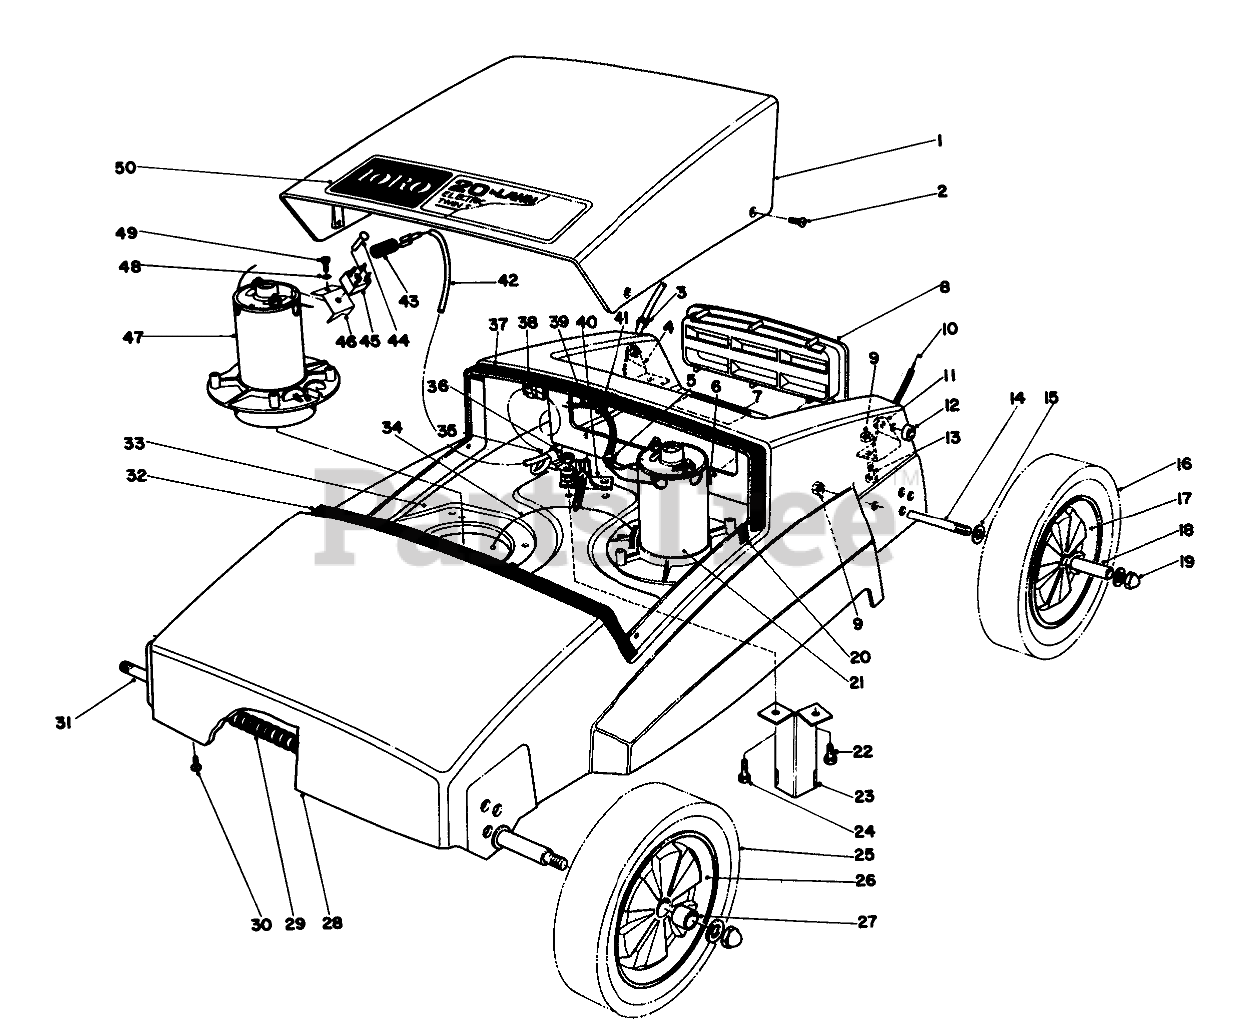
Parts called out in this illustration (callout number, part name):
1	Cover
3	5/16 ID BSHG
4	Handle Bracket R.H.
5	TIE-CABLE
6	Nut-Push On
7	Decal-Warning
8	Louver
9	NUT-LOCK, CONE
10	Control Cable-Upper
11	Handle Bracket L.H.
12	Spacer-Handle
13	SCREW-HH
14	Axle-Rear
15	WASHER-FLAT
17	Rear Wheel-8" (Incl. Ref. #16 & 27)
18	Spacer-Wheel
19	Locknut
20	Nut-Push On
21	Motor L.H. (C.W.)
22	SCREW-HH
23	Blade-Cut Off
24	SCREW-HH
25	Tire 7"
26	Front 7" (Incl. Ref. #25 & 27)
27	BUSHING
28	Housing-Mower
29	COVER-SHAFT, DRIVE
30	Screw
31	Axle-Front
32	Cushion-Front
34	Control Cable-Lower
35	WIRE CLAMP
36	NUT-LOCK, CONE
37	Cushion-Rear
38	Clip-Power Cord
39	Sleeve-Motor Lead
40	Bracket-Control
41	Clip-Motor Lead
42	Wire Harness
43	Sleeve-Terminal Cover
44	POP RIVET 3/16X.375LG
45	Rectifier
46	Bracket-Rectifier
47	Motor R.H. (C.C.W.)
48	WASHER-LOCK / EXT
50	Decal-Cover
